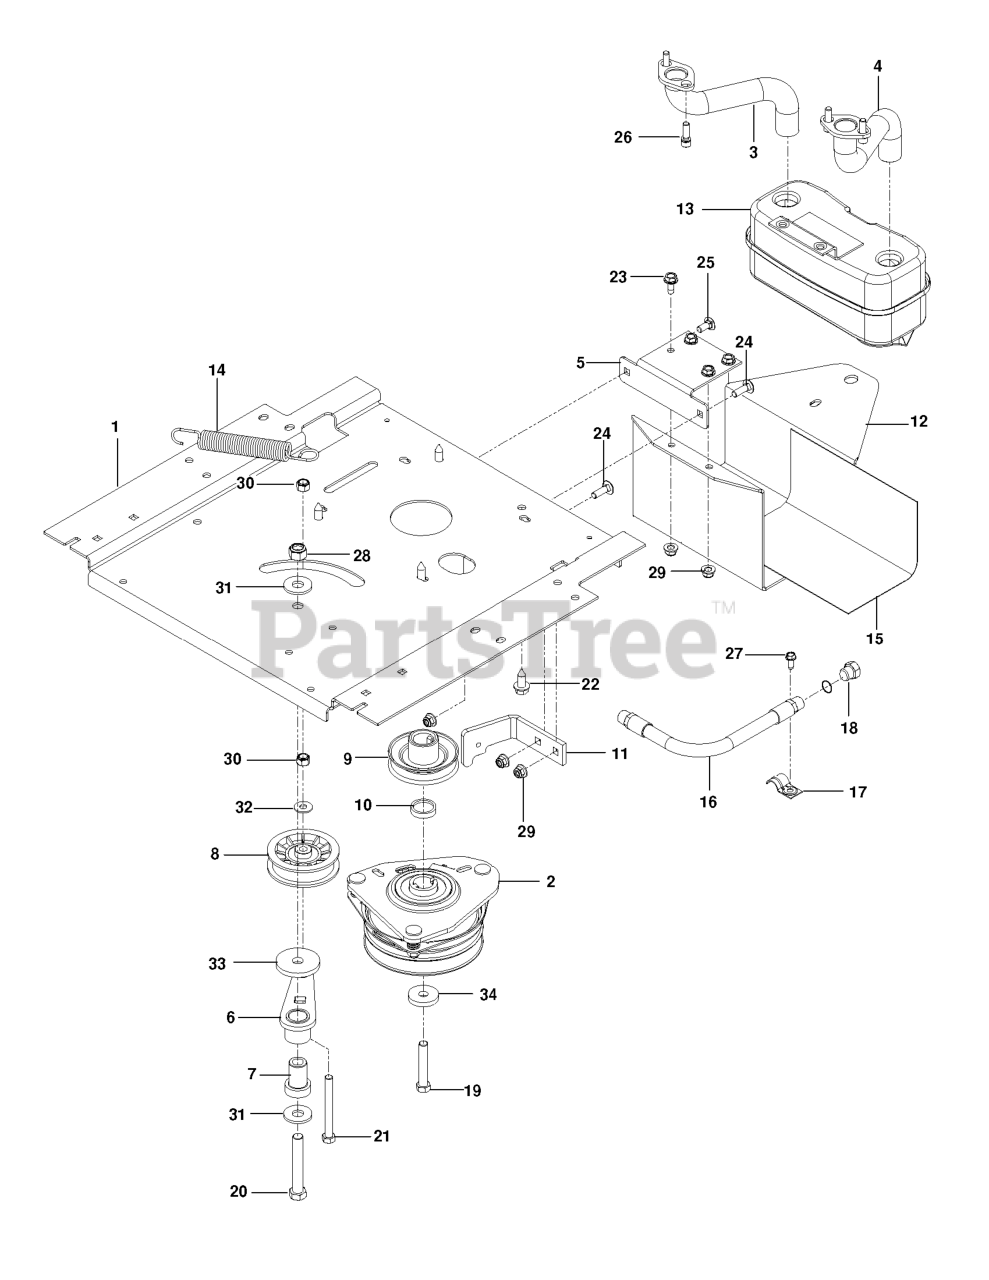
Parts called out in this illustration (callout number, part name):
1	PLATE, ENGINE BLK
2	CLUTCH.ELECTRIC.LT.48"*
3	RP.PIPE-EXHAUST RH
4	RP.PIPE-EXHAUST LH
5	BRACKET, MUFFLER, BLACK
6	RP.IDLER ARM WELDMENT
7	IDLER SPINDLE
8	PULLEY, IDLER RAKE & ZTR
9	PULLEY, ENGINE
10	SPACER, HUB PULLEY
11	CLUTCH STOP OGR BLK
12	GUARD.MUFFLER.BLACK
13	MUFFLER ASM TWIN
14	SPRING, DECK DRIVE
15	HEAT SHIELD
16	HOSE.ASSEMBLY.OIL.DRAIN
17	CLAMP
18	PLUG OIL DRAIN
19	HCS 7/16-20 X 2.5 GR8
20	HCS 1/2C X 3 1/4
21	HCS 3/8-16X3 1/2 GR5
22	HHFS 3/8-16 X 1.0 THD FORMING
23	BOLT 5/16-18 X 3/4
24	RHSNB 5/16C X 1
25	BOLT 5/16C X 3/4" CARRIAGE
26	SCREW.SOCKET.HEAD.5/16-18
27	SCREW 1/4 X 5/8
28	NUT 1/2-13 HEX NYLOC ZD
29	5/16-18 NYLOC FLANGE NUT
30	NUT 3/8-16 NYLOC
31	WASH USS FLAT 1/2
32	WASHER 5/16 FLAT
33	HEAVY WASHER
34	CLUTCH, WASHER
